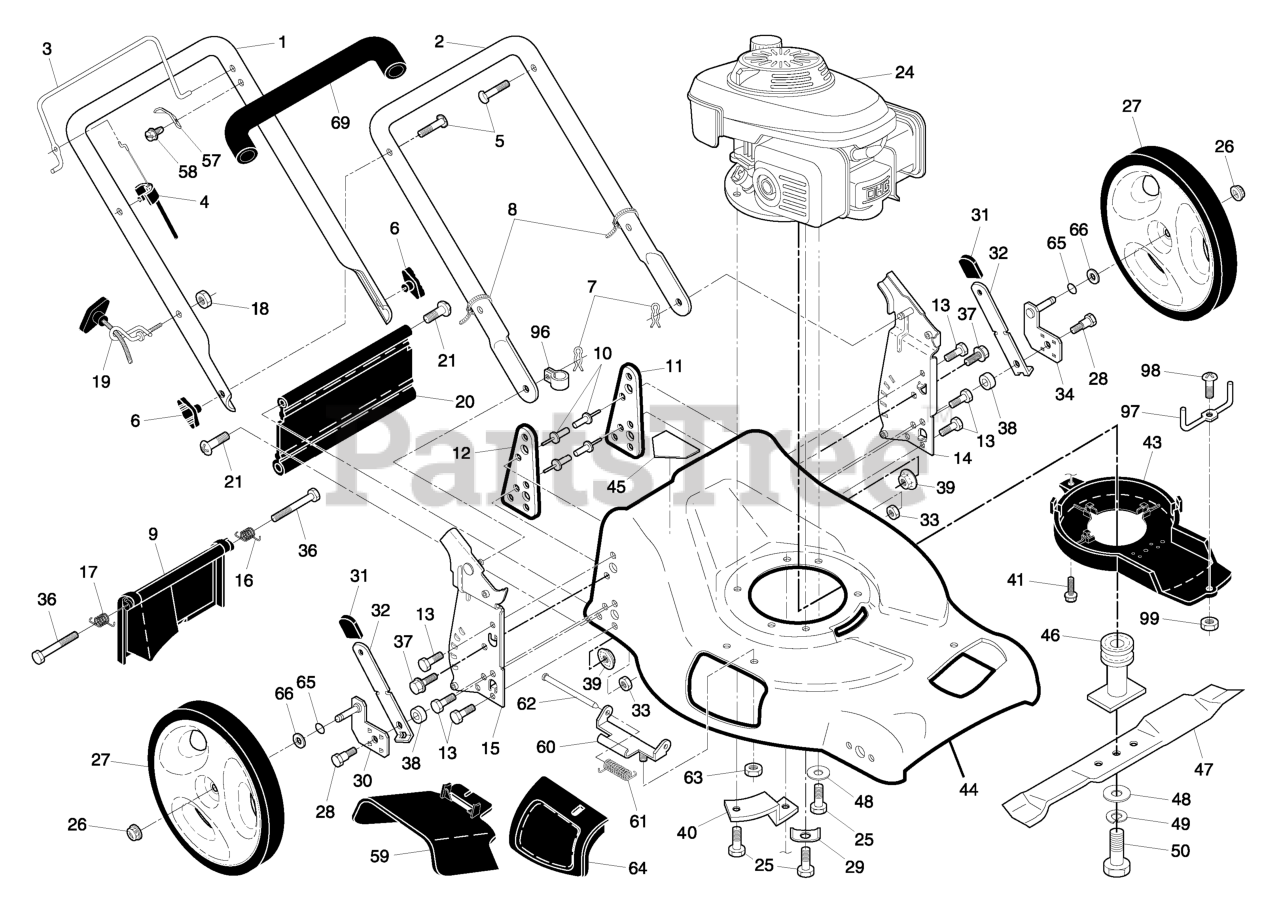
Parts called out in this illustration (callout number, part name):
1	RP HANDLE.ASM.UPPER.W/GRI
2	LOWER HANDLE
3	BAIL.DSTRT.FL.AW.CREAS.ORANGE
4	CABLE.ENGINE BRAKE.MZR
5	BOLT, HANDLE 5/16-18X1.75
6	HNDL.KNOB.GRAY
7	HAIRPIN COTTER
8	TIE GUIDE
9	REAR DOOR ASSEMBLY
10	RIVET BLIND
11	SUPPORT BRACKET LH
12	BRACKET.SUPRT.RH.21.FWGD
13	SCREW 14-20 X 5/8
14	BRKT.ASM.HNDL.21FGD.EZ
15	BRKT.ASM.HNDL.21FGD
16	SPRING.REAR.DOOR.EZ.21.LT
17	SPRING.REAR.DOOR.EZ.21.RT
18	NUT
19	RB GUIDE.ROPE.STD.BLK.ZIN WSL
20	REAR SKIRT
21	HINGE SCREW
25	BOLT 3/8-16X1-1/8
26	NUT
27	WHEEL ASSY
28	SHOULDER BOLT
29	WASHER.ENGINE.BZP
30	ARM.ASM.AXLE.H/W,RR.BZ
31	SELECTOR KNOB
32	SPRING.SELECTOR.21.FWG.ZINC
33	NUT.71038.31-18.HEX.NYLOCK
34	ARM.ASM.AXLE.H/W.LR.BZ
37	BOLT.FIN.HEX.5/16-18X3/4
38	WASHER.FLAT.34X1.38X22
39	NUT, HEX FLANGE 5/16-18
40	BRACKET
41	SCREW.HEX.WSH
43	DEBRIS SHIELD
44	HOUSING.21.FWD.ORANGE.WALK
45	DANGER DECAL
46	RP ADAP.BLDE/PULL
47	BLADE.21.PUSH/RWGD/FWG
48	WASHER,HARDEN
49	LOCKWASHER
50	SCREW, HEX HD 3/8-24 X 1-3/8
57	BRACKET UPSTOP
59	DEFLECTOR.CLIPPIN.21.FGD
60	BRACKET.ASM.HINGE.21.FWGD.
61	SPRING.TORSION
62	ROD.HINGE.21
63	LOCKNUT.NYLOC.1/4-20
64	DOOR.MULCH.21.REAR.FWGD
65	O-RING..070X.487.NEOPRENE
66	WASHER.FLAT.1/2
69	GRIP.HANDLE.FOAM.WIDE.(1 SIDE)
96	CLIP.CABLE.BLK
97	KEEPER.BELT.FGD
98	SCREW.#8.MACH
99	NUT.HEX.#8
